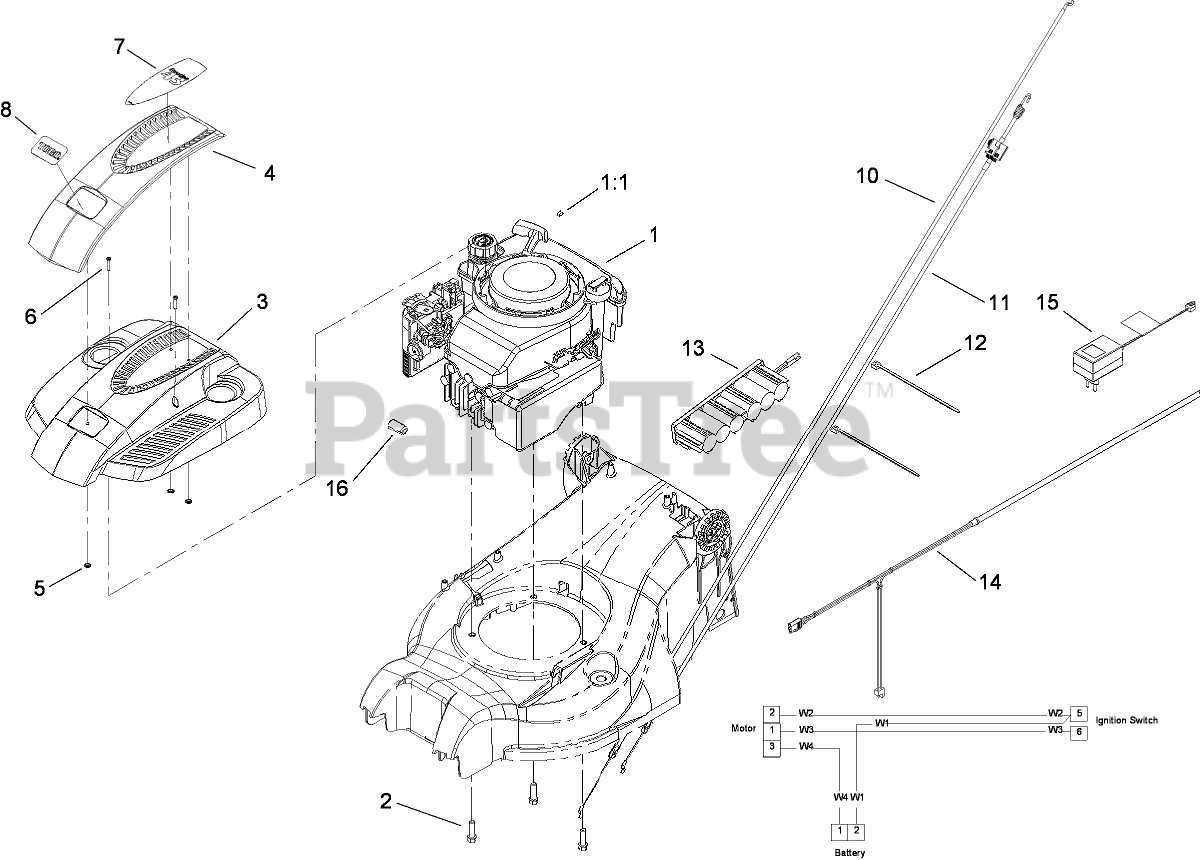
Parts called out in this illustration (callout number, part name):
1:1	STOP-ROPE
2	SCREW-TAPTITE
3	SHROUD-ENGINE
4	COVER-SHROUD
5	CLIP-PUSH
6	SCREW-PPH
10	CABLE-BRAKE
11	CABLE-TRACTION
12	TIE-CABLE
13	BATTERY
14	HARNESS-WIRING
15	CHARGER-EUROPEAN, 12V DC
16	FERRITE-SNAP ON
